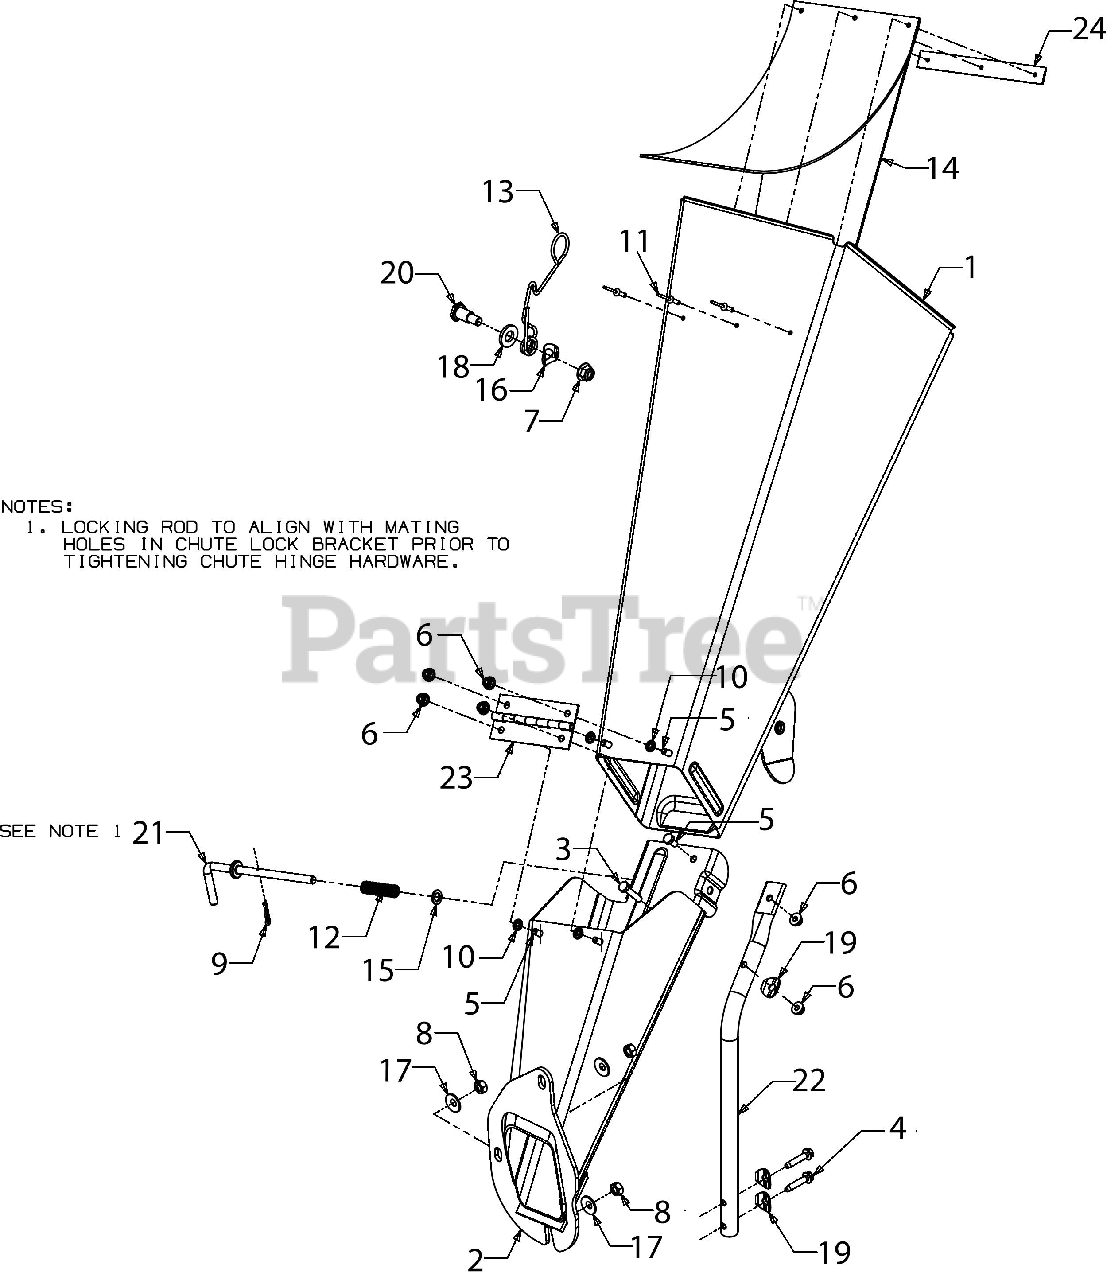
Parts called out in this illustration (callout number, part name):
1	CHUTE ASSEMBLY (UPPER)
2	LOWER CHIPPER CHUTE
3	HEX SCREW 1/4-20 x 1.25
4	SCREW 1/4-20 x 1.25
5	SCREW 1/4-20X.5 GR5
6	FLANGE LOCK NUT
8	HEX NUT
9	COTTER PIN .072 DIA
10	RETAINER-BOLT .25ID x .50OD
12	COMPRESSION SPRING
13	TORSION SPRING
14	CHUTE FLAP
15	FLAT WASHER
16	SPRING WASHER .50 x 1.0 x .022
17	BELL WASHER .337 X.867 x .057
18	FLAT WASHER .510 x 1.000 x .125
19	SADDLE WASHER
20	SHOULDER SCREW .500 DIA x .685
22	CHUTE SUPPORT
23	CHIPPER CHUTE HINGE
24	FLAP STRIP
